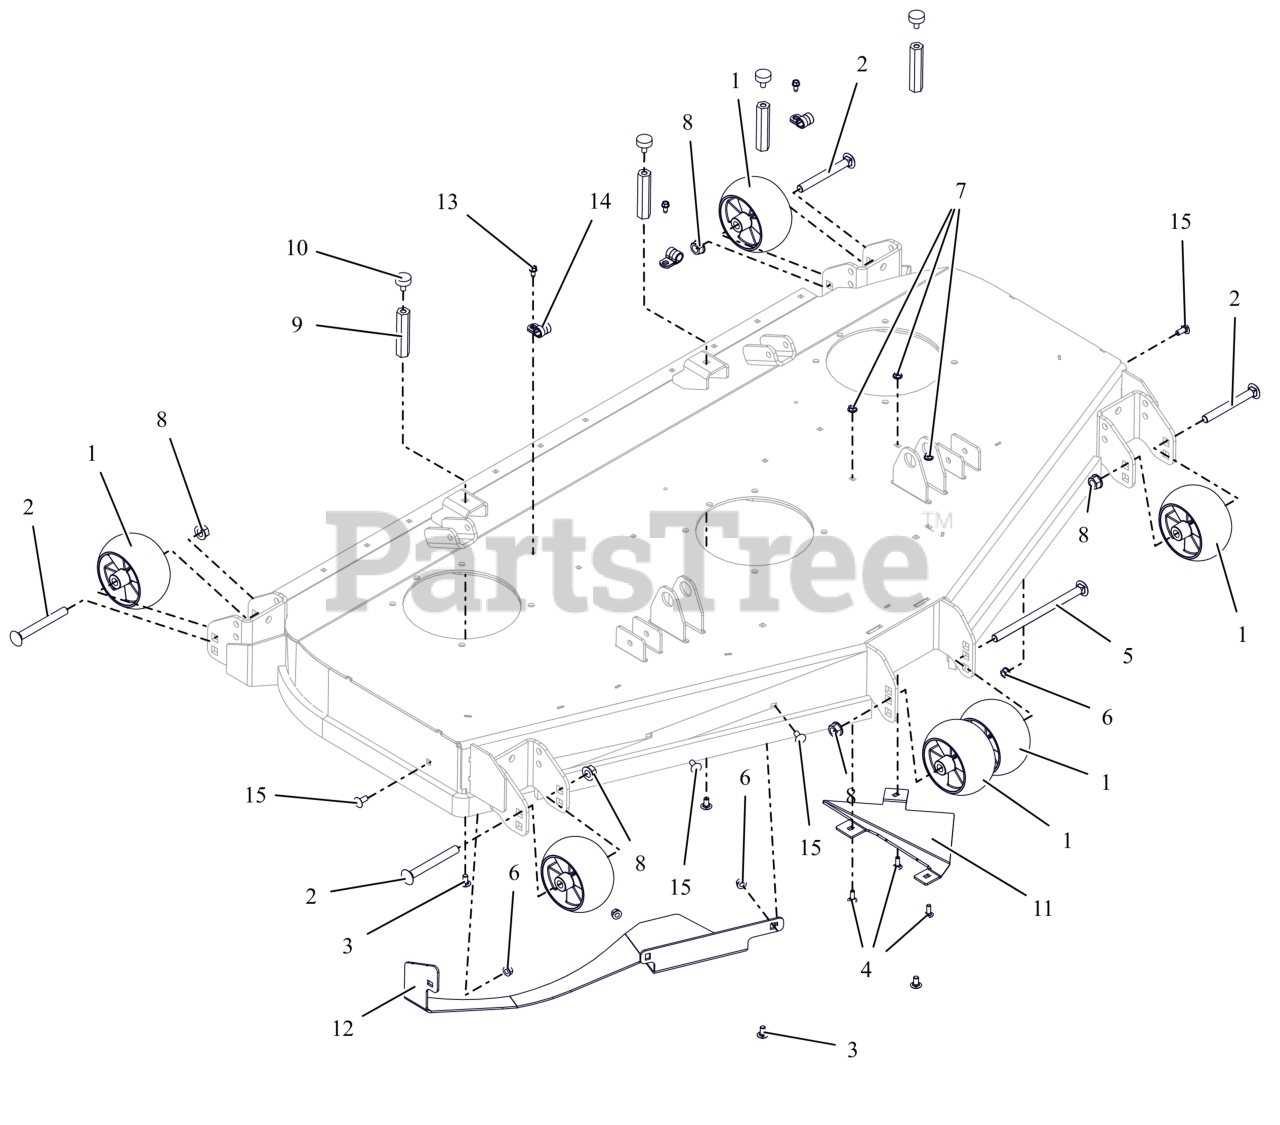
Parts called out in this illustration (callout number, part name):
1	WHEEL, ANTI SCALP - 5X3 CTR W/RIBS
2	BLT,RHNS .50-13X4.50 G5 ZCC NS
3	BTL,RHSSN .313-18 X 0.625 G5 ZCC
4	BLT, RHSN .25-20X.750 G5 ZCC
5	BLT,RHSN .50-13X8.00 G5 ZCC NS
6	NUT,LK-CTR-FLG .31-18 GF ZCC
7	NUT-LK-CTR-FLG .25-20 ZC120
8	NUT-LK-CTR-FLG .500-13 GG ZCC
9	NUT, COUPLING .312-18 X 3.375
10	BUMPER, RUBBER
11	BAFFLE, INSERT TRIANGLULAR (RED)
12	DEFLECTOR, BAFFLE BOLT-IN (RED)
13	SCR-TAP .25-20X.50 HWH ZCC
14	CLAMP, CUSHIONED STEEL
15	BLT, RHSSN.31-18X.750 G5 ZCC
